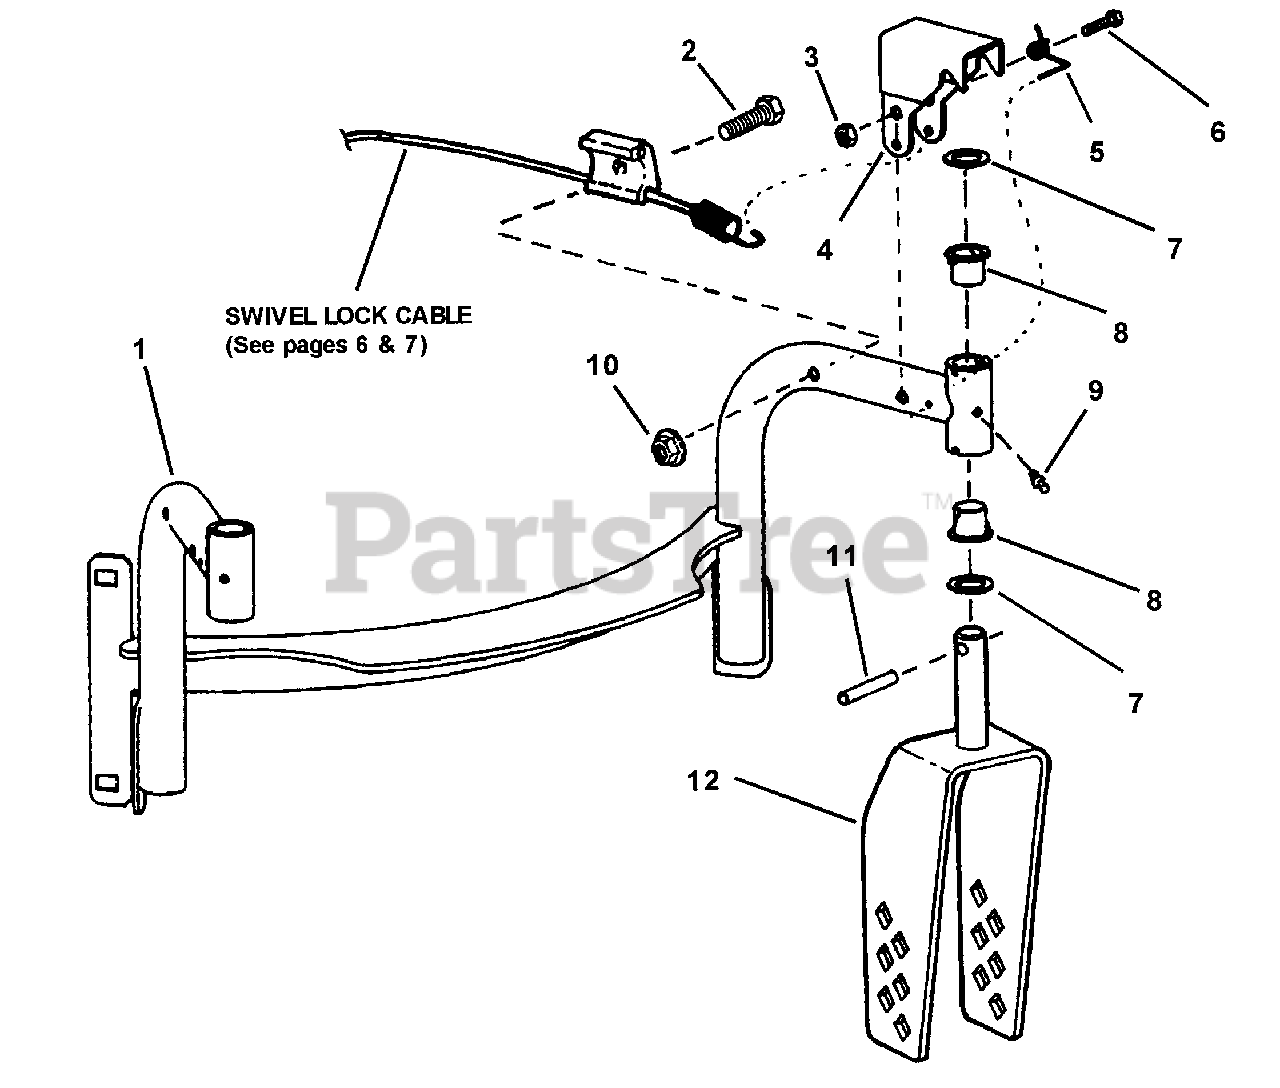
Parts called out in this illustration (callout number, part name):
1	WELDMENT, Front Bracket
2	SCREW, 1/4-20 x 1-1/2" Hex Cap, Grade 5
3	NUT, 1/4-20 Hex Lock
4	BRACKET, Swivel Lock
5	SPRING, Torsion
6	BOLT, 1/4-20 x 2" Hex, Grade 5
7	WASHER, 41/64" Flat
8	BUSHING, 5/8" Nylon
9	LUBE FITTING, Straight (press-fit for .187 dia. Hole)
10	NUT, 1/4-20 Hex Nylok
11	PIN, 1 /4 x 1-3/4" Roll
12	WELDMENT, L.H. Swivel Bracket
